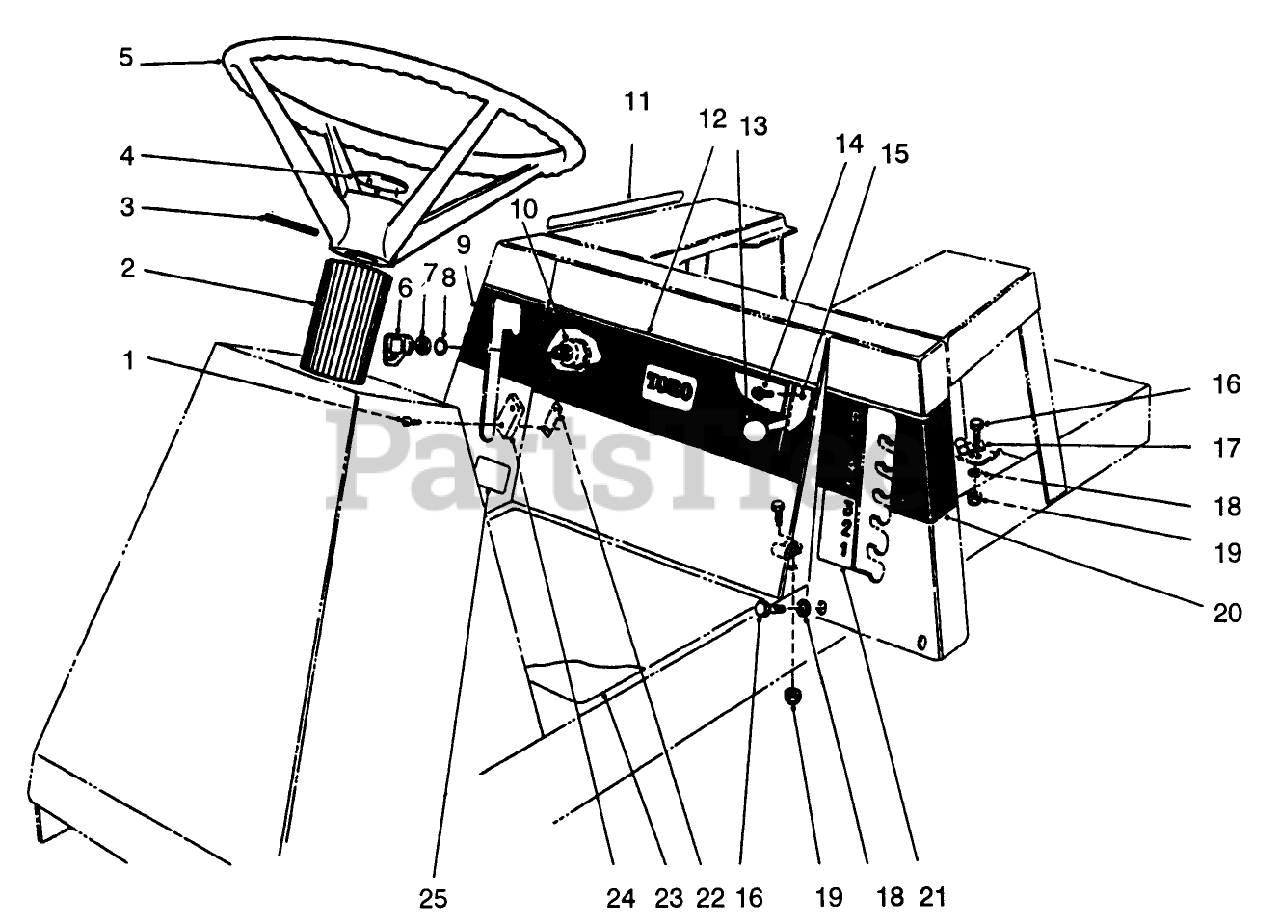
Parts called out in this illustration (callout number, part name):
1	SCREW-SPH
2	COVER-STEERING SHAFT
3	PIN-ROLL
4	INSERT-STEERING WHEEL, TORO
5	STEERING WHEEL ASM
6	KEY-IGNITION
7	NUT-HH
8	WASHER-LOCK
9	DECAL-UPPER DECK ENGAGE
10	SWITCH-STARTER
11	DECAL - SHIFT PATTERN
12	DECAL-FRT SEAT CONTROLS
13	KNOB-CONTROL
14	SCREW-HWHTF
15	THROTTLE CONTROL
16	SCREW-HH
17	CLAMP
18	WASHER-PLAIN
19	NUT-LOCK, NI
20	DECAL - UPPER HOC
22	NUT-SPEED
24	SWITCH-MICRO
25	DECAL-LOWER DECK ENGAGE
